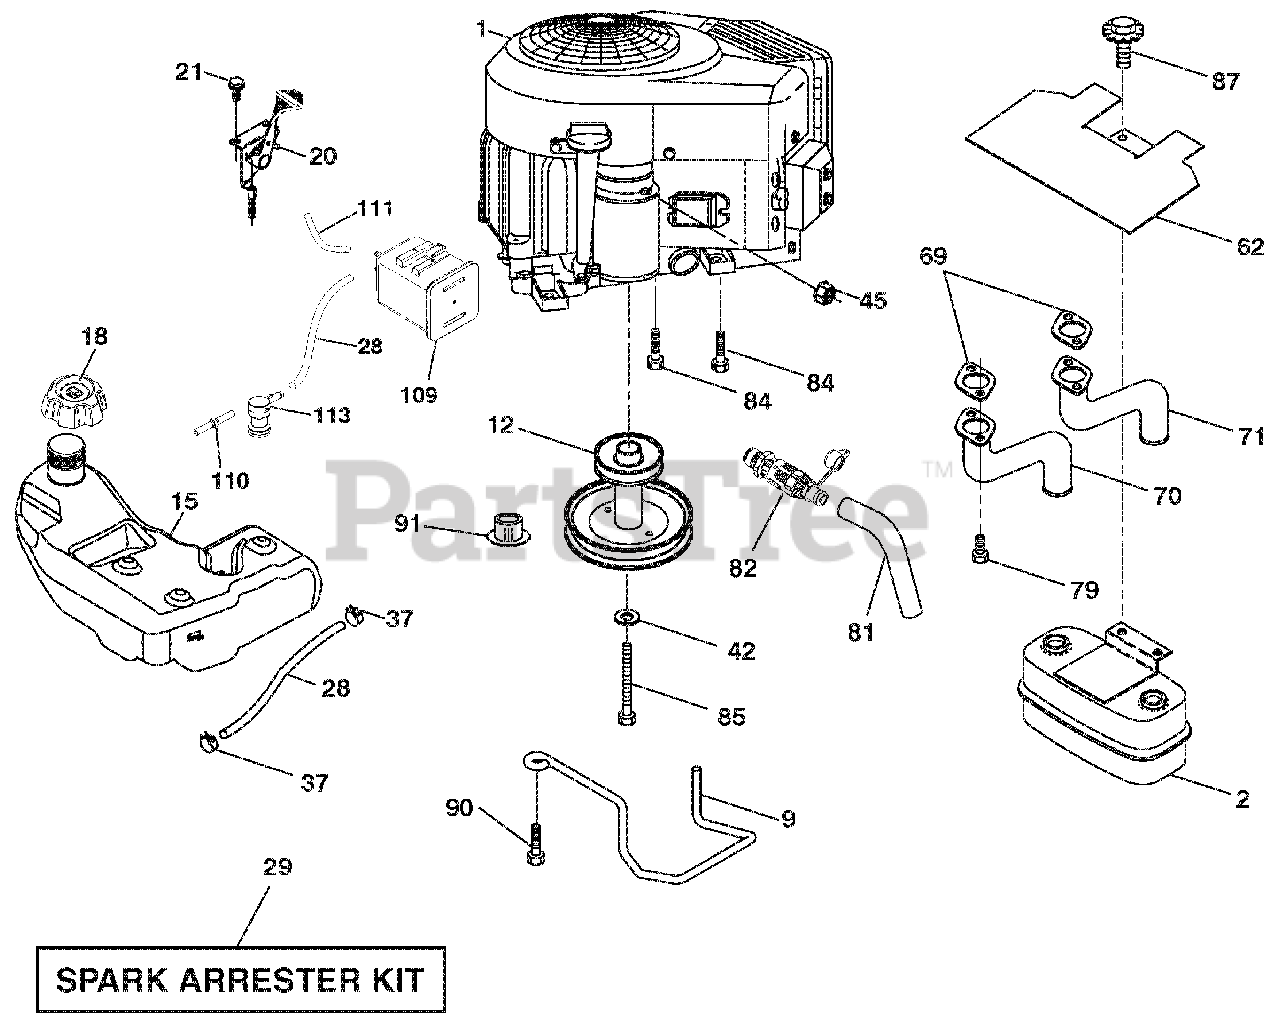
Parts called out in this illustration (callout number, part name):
1	ENGINE BRIGGS MODEL NO. 406777-1404-G1 (ORDER PARTS FROM ENGINE MANUFACTURER)
2	MUFFLER ASM.TWIN.LO-TONE
9	KEEPER.BELT.ENGINE.4.25"NSTG
12	PULLEY ENGINE
15	TANK.FUEL.ASM.3.00 GA.
18	CAP FUEL
20	CONTROL THROTTLE/CHOKE
28	LINE.FUEL.64"REAR.EMIS.CA.LP
29	KIT.SPARK ARRESTOR(392390 B&S)
37	CLAMP.HOSE.BLK.
42	WASHER.LOCK.HVY HLCL.SPR.7/16
45	Nut, Keps Hex 1/4-20 unc
62	SHIELD.HEAT.MUFFLER.CV-INTEK
69	GASKET MUFFLER
70	EXHAUST TUBE LH
71	EXHAUST TUBE RH
79	SCREW SOCKET HEAD 5/16-18 X 1
81	TUBE.DRAIN.OIL.EASY
82	VALVE OIL DRAIN
84	Screw 3/8-16 x <
85	BOLT.HEX.7/16-20X4XGR5-1.5THR.
87	BOLT.5/16-18UNCX3/4 W/SEMS.BLK
90	SCREW.3/8-16X1.SMGML.TAP/R.BLK
91	BUSHING.1.375OD.HEYCO 2210
109	CANISTER.CARBON.FILTER ASM.TEX
110	VALVE.ASM.ANTI-SLOSH
111	PURGE.LINE.CARB
113	VALVE.SLANT.CARTIDGE
